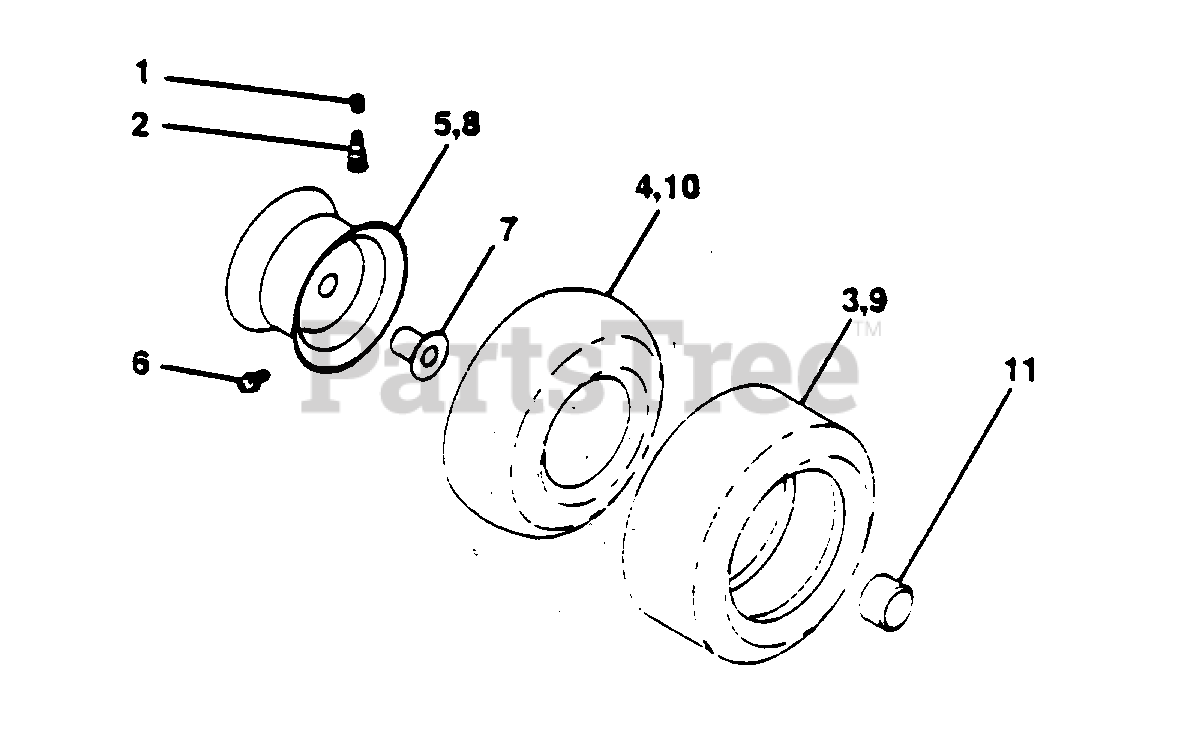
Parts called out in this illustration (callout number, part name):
1	Cap Valve Tire
3	Tire F Ts 15 X 60 - 6 Service
4	Tube Front (Service Item Only)
5	Rim Asm 6" front Service
6	Fitting Grease (Front Wheel Only)
7	Bearing Flange (Service Item Only)
8	Rim Asm 8" rear Service
9	Tire R Ts 18x9 5-8 C Service
10	Tube Rear (Service Item Only)
11	Cap Axle Blk 1 50 X 1 00
